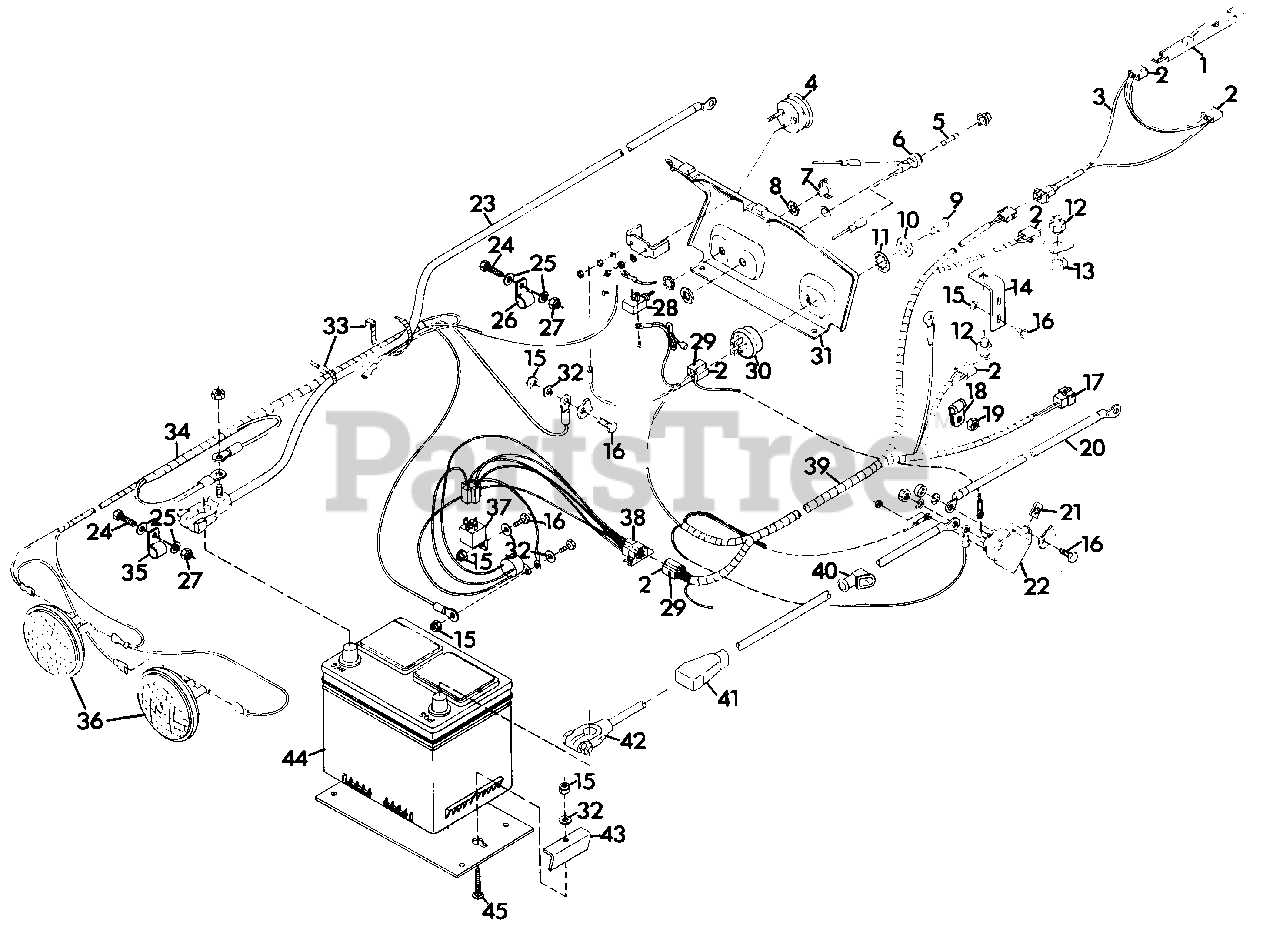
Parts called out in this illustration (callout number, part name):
1	SWITCH, SEAT
2	TERMINAL
3	HARNESS, WIRING SEAT SWITCH
4	GAUGE, AMMETER
5	FUSE, 30 AMP AGC 30
6	FUSE, PANEL
7	KNOB, LIGHT SWITCH
8	NUT, SPECIAL LIGHT SWITCH
9	KEY, IGNITION SWITCH
10	NUT, JAM 9/16-24
11	WASHER, LOCK 9/16 INT. TOOTH
12	SWITCH, INTERLOCK
13	NUT, STAMPED 9/16-18
14	BRACKET, SWITCH
15	NUT, LOCK 1/4-20
16	BOLT, HEX 1/4-20X.75
17	CONNECTOR
18	CLAMP
19	NUT, LOCK 3/8-16
20	CABLE, STARTER
21	NUT, SPEED 1/4-20
22	SWITCH, MAGNETIC
23	CABLE, NEGATIVE BATTERY
24	BOLT, HEX 5/16-18X1.00
25	WASHER, FLAT .344X.688X.065
26	CLAMP, NYLON
27	NUT, LOCK 5/16-18
28	SWITCH, LIGHT
29	CONNECTOR
30	SWITCH, IGNITION
31	PANEL, INSTRUMENT
32	WASHER, FLAT .281X.625X.065
33	TIE, CABLE
34	HARNESS, WIRING GROUND AND LIGHT
35	CLAMP, NYLON
36	HEADLIGHT
37	RELAY
38	MODULE, TIME DELAY
39	HARNESS, WIRING
40	BOOT, BATTERY CABLE
41	COVER, BATTERY TERMINAL
42	CABLE, BATTERY TO MAGNETIC SWITCH
43	CLAMP
44	BATTERY, 12 VOLT
45	BOLT, 1/4-20X1.75 RD HD SQ NK
